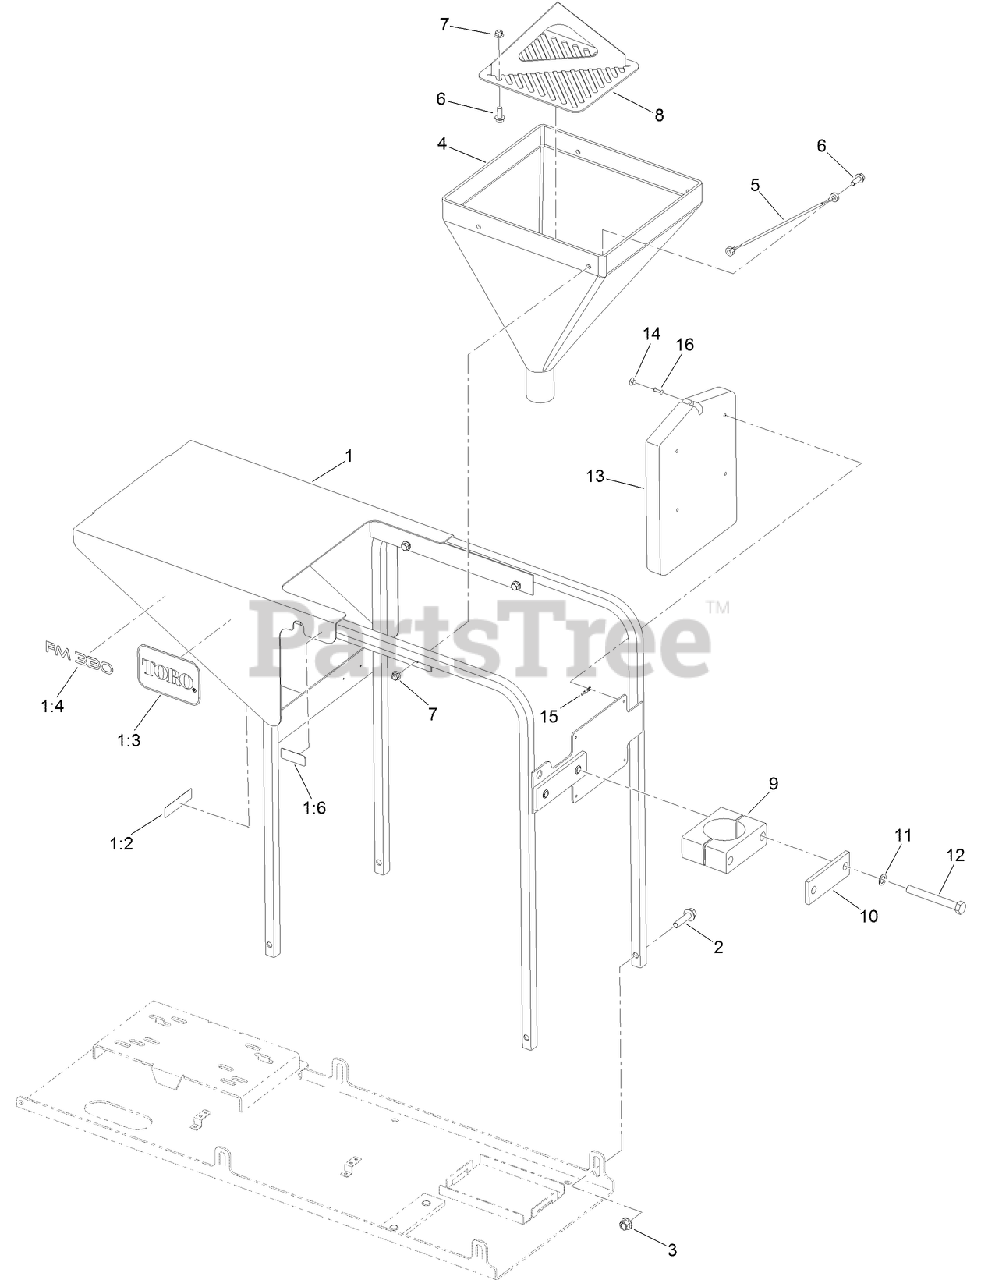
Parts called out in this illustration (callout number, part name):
1	HOPPER SUPPORT ASM
1:2	DECAL-ARRESTER, SPARK
1:3	DECAL
1:6	Decal-Warning, Puncture
2	SCREW-HHF
3	NUT-LOCK
4	HOPPER-MIX
5	LANYARD-GATE
6	SCREW-HHF
7	NUT-HF, NI
8	CUTTER-BAG
9	CLAMP-PIPE
10	PLATE-CLAMP
11	WASHER-FLAT
12	SCREW-HH
13	HOLDER-MANUAL, OPERATOR
15	LANYARD
16	POST-MANUAL
